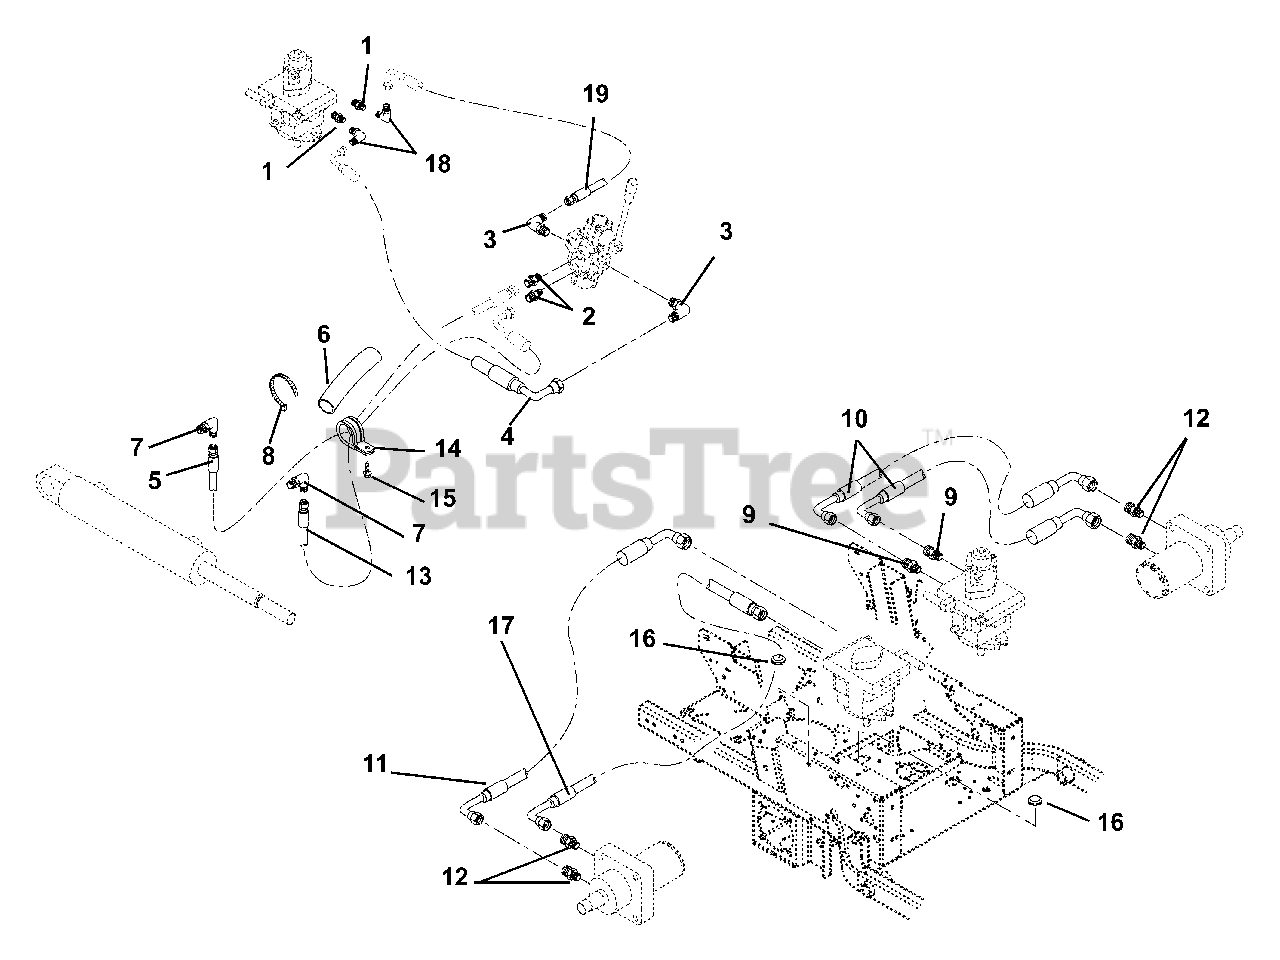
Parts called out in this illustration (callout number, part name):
1	FITTING, HYD (4 F5OLO)
2	FITTING, HYD (4-6 F5OLO)
3	FTG, HYD ELBOW M4F-M8O
4	HOSE,HYD .25-19-2K F04F9-F04F9
5	HOSE,HYD .25-47-2K FO4F0-FO4F0
6	SLEEVE, PROTECTIVE
7	FITTING, HYD (4 C5OLO)
8	CABLE TIE LG 5-1/2
9	ADPTR,FACE SEAL 8X8 1/2 O-RING
10	HOSE,HYD .50-19-2K F08F9-F08F9
11	HOSE,HYD .50-20-2K F08F0-F08F0
12	FTG, HYD STR M10O-M8F
13	HOSE,HYD.25-42-2K F04F0-F04F4
14	CLAMP, COUSHIONED STEEL REV
15	@SCR-TAP .25-20X.50 HWH TR YWZ
16	GROMMET 1.25ID X 1.5OD
17	HOSE,HYD .50-17-2K F08F0-F08F9
18	FTG, HYD ELBOW F4F-M4O
19	HOSE,HYD .25-15-2K F04F9-F04F0
